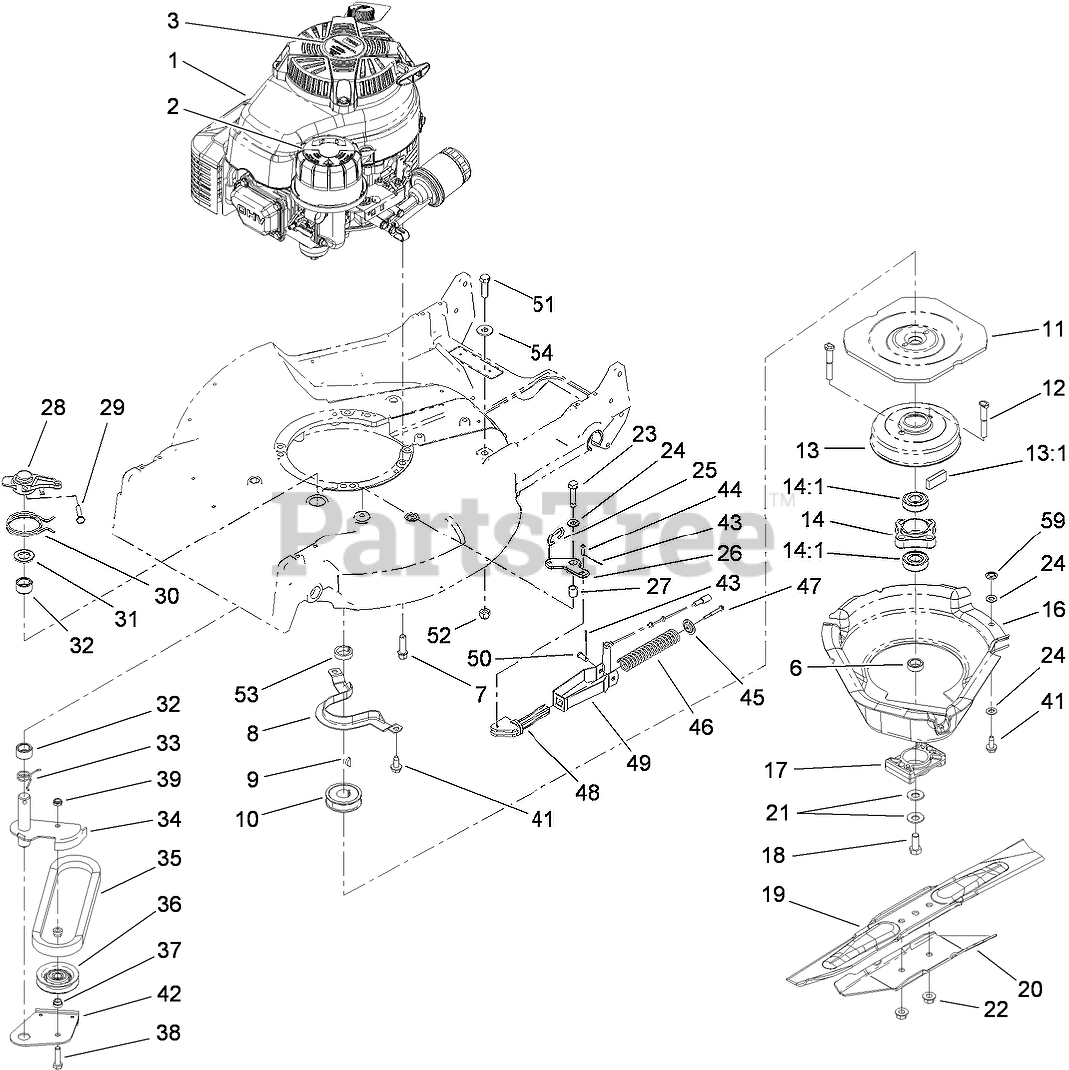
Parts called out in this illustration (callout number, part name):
1	ENGINE-KAWASAKI, FJ180V-AM07-M
6	SPACER-SHAFT, OUTPUT
7	SCREW-TAPTITE
8	BRACKET-GUIDE, BELT
9	KEY-WOODRUFF
10	PULLEY-DRIVER
11	FLYWHEEL-BBC
12	BOLT-BLADE
13	BRAKE DRUM ASM
13:1	DAMPENER-VIBRATION
14	HUB ASM
14:1	BEARING-BALL
16	SHIELD
17	SPACER-BLADE
18	SCREW-HH
19	BLADE-21 INCH
20	STIFFENER-BLADE
21	WASHER-SPRING
22	NUT-LOCK
23	SCREW-HH
24	WASHER-PLAIN
25	LINK-CONTROL
26	BELLCRANK
27	SLEEVE-BELLCRANK
28	LEVER
29	SCREW-HH
30	SPRING-TORSION
31	WASHER
32	BEARING
33	SPRING-TORSION
34	ARM-IDLER
35	V-BELT
36	PULLEY-IDLER
37	SPACER-PULLEY, IDLER
38	SCREW-HH
39	NUT-LOCK, NI
41	SCREW-HWHTF
42	BRAKE PLATE ASM
43	PIN-COTTER
44	PIN-SPRING
45	RETAINER-SPRING
46	SPRING
47	SCREW-HWHTF
48	GUIDE-SPRING
49	BRACKET-SPRING
50	PIN-CABLE
51	SCREW-HH
52	NUT-LOCK, NI
53	SPACER-PULLEY
54	WASHER-HARDENED
59	NUT-PUSH
